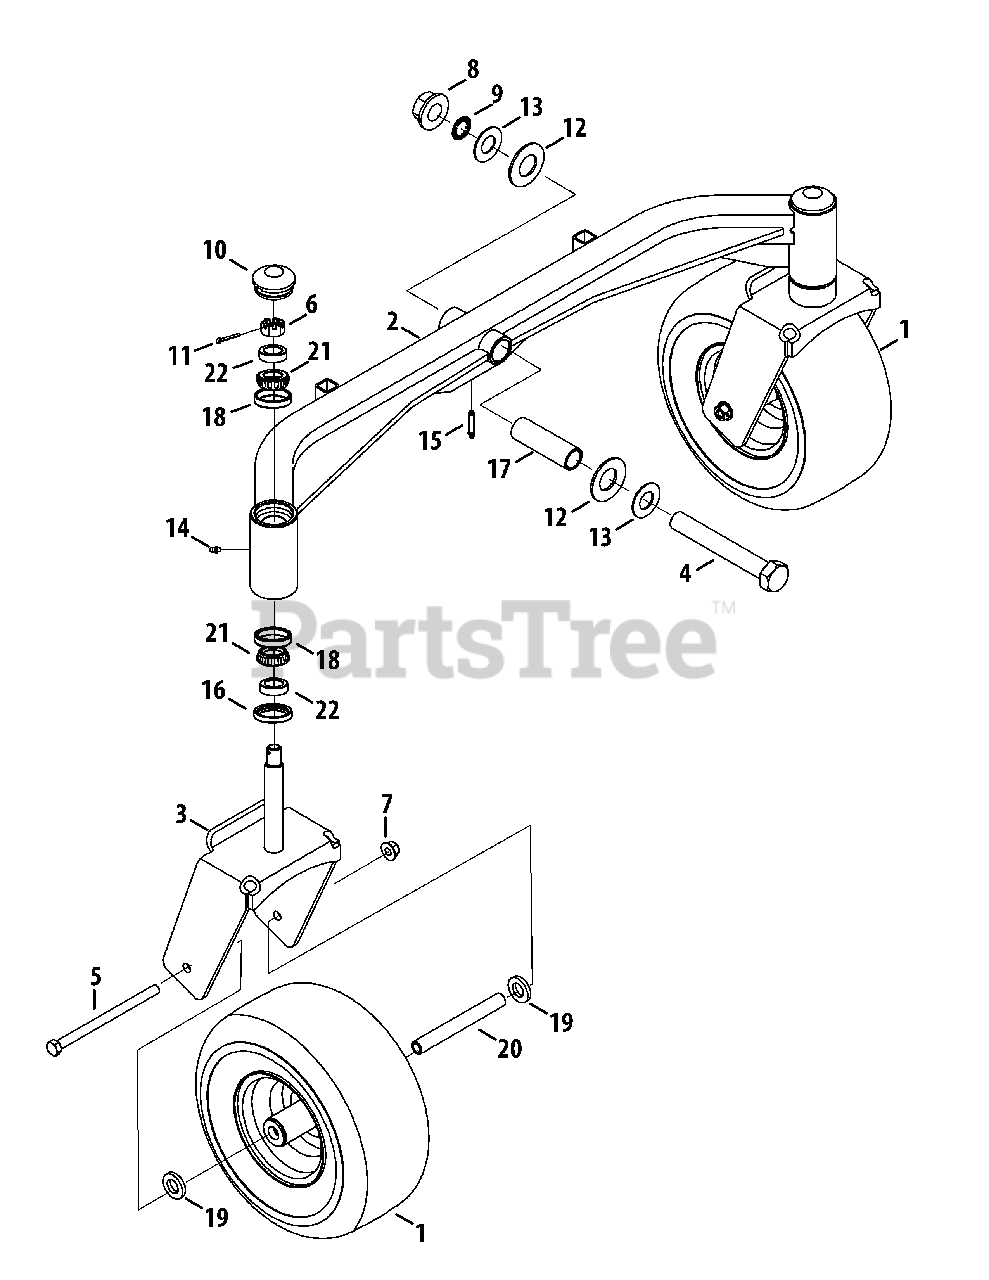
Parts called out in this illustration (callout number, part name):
1	Wheel Assembly, 13 x 6.50-6
2	Front Axle (54" & 60")
3	Yoke, Caster Wheel
4	Hex Cap Screw, 1-14 x 7.0
5	Hex Cap Screw, 1/2-13 x 7.75
6	Nut, 3/4-16, Slotted
7	Nut, 1/2-13, Flangelock
8	Nut, 1.0-14, Flangelock
9	Retainer Ring
10	Axle Grease Cap
11	Cotter Pin, 5/32 x 1.25
12	Bell Washer, 1.25 x 2.50 x .180
13	Washer, 1.00 x 2.00 x .075
14	Grease Fitting, 1/4-28
15	Grease Fitting, 1 39/64
17	Spacer, 1.005 x 1.247 x 4.1
18	Cup Bearing
19	Spacer, .812 ID x .218 LG
20	Spacer, .515 x .749 x 6.313
21	Cone Bearing
22	Spacer, 1.00 x 1.50 x .437
